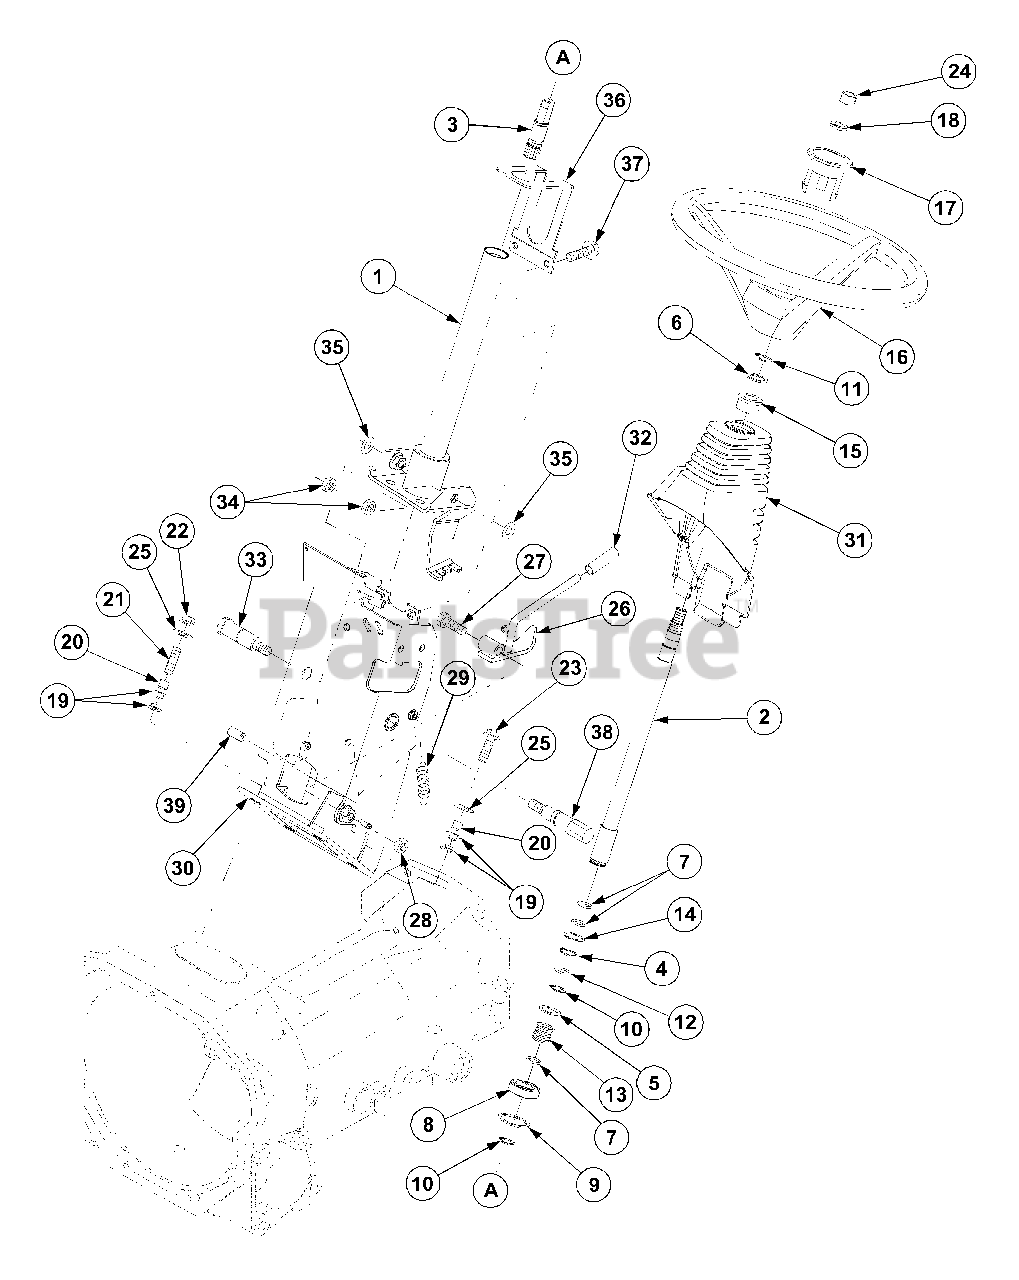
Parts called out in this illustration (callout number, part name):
1	Mast,Steering
2	Shaft,Steering
9	C-ring
10	C-ring
11	C-ring
15	Bushing Column
16	Steering Wheel
18	Washer,Spring
23	Bolt,w/Washer
30	Bracket,Mast
31	Boot,Steering
37	Bolt,w/Washer
